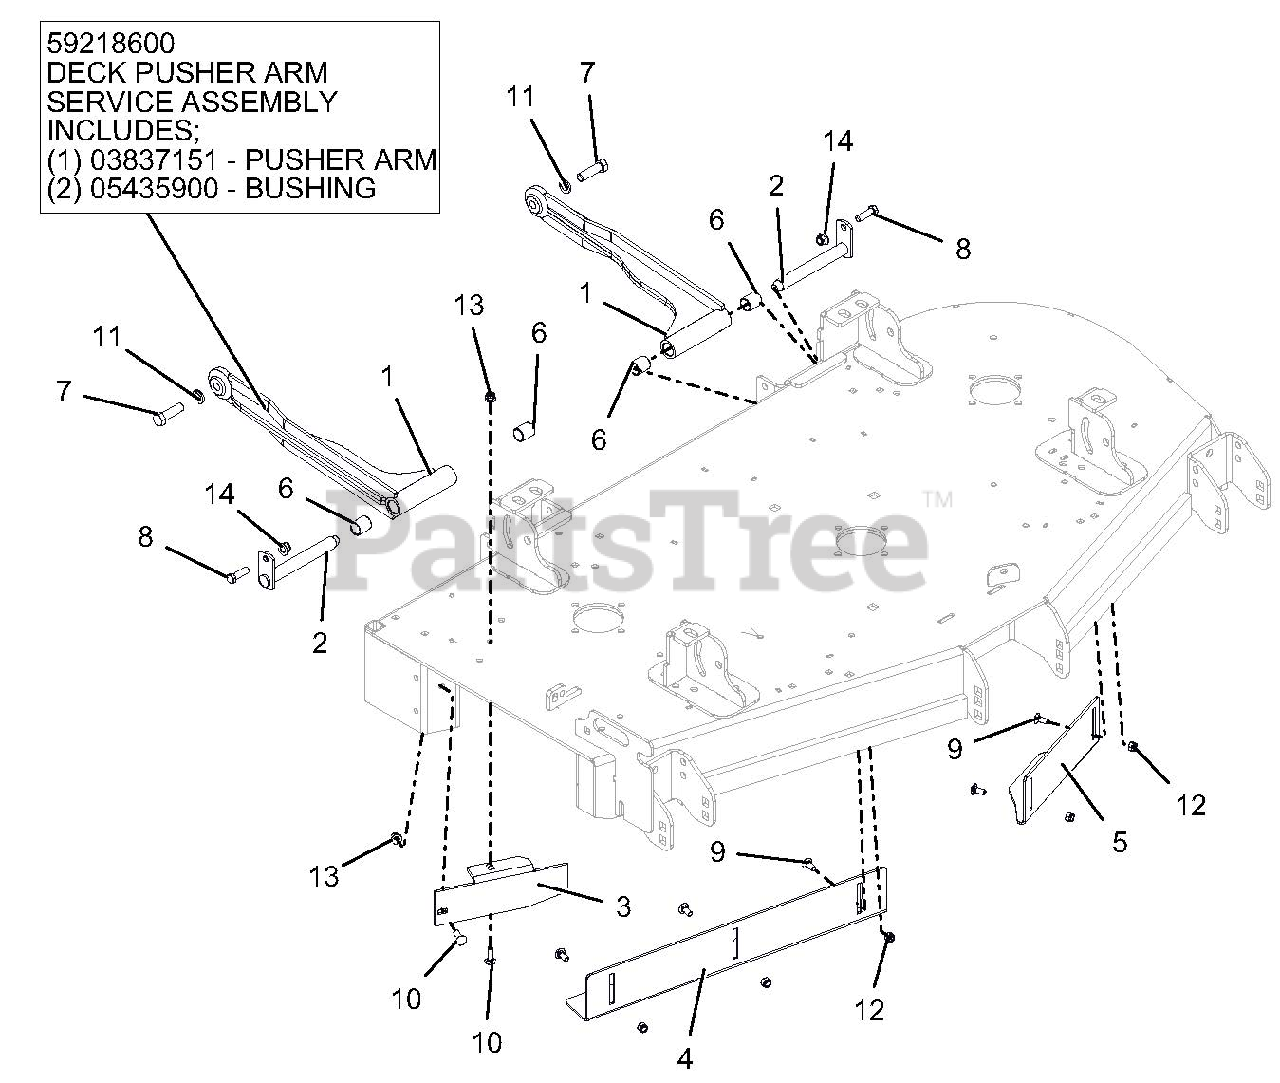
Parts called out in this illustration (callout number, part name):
1	WMT, DECK STABILIZER ARM-BLACK
1	DECK PUSHER ARM SERVICE ASSEMBLY
1	PUSHER ARM
1	BUSHING
2	WLDMT, MOWER MTG. PIN
3	BAFFLE, 52" DISCHARGE-RED
4	BAFFLE, 52" RH VACUUM-BLACK
5	BAFFLE, 52" LH VACUUM-BLACK
6	BRG, .750 X .875 X 1.000
7	BLT-HEX .50-13X1.75 GR5 YWZC EP80
8	BLT-HEX .38-16X1.25 GR5 YWZC
9	BLT-RDHDSQNK .31-18X.75 G5 YWZC
10	BLT-RDHDSQSHNK .31-18X1.00 G5 Y
11	WSHR-LK .50X.125 REG YWZC
12	NUT-LK-NYL .312-18 YWZC
13	NUT-LK-NYL-FLG .31-18 YWZC
14	NUT-LK-NYL-FLG .38-16 YWZC
